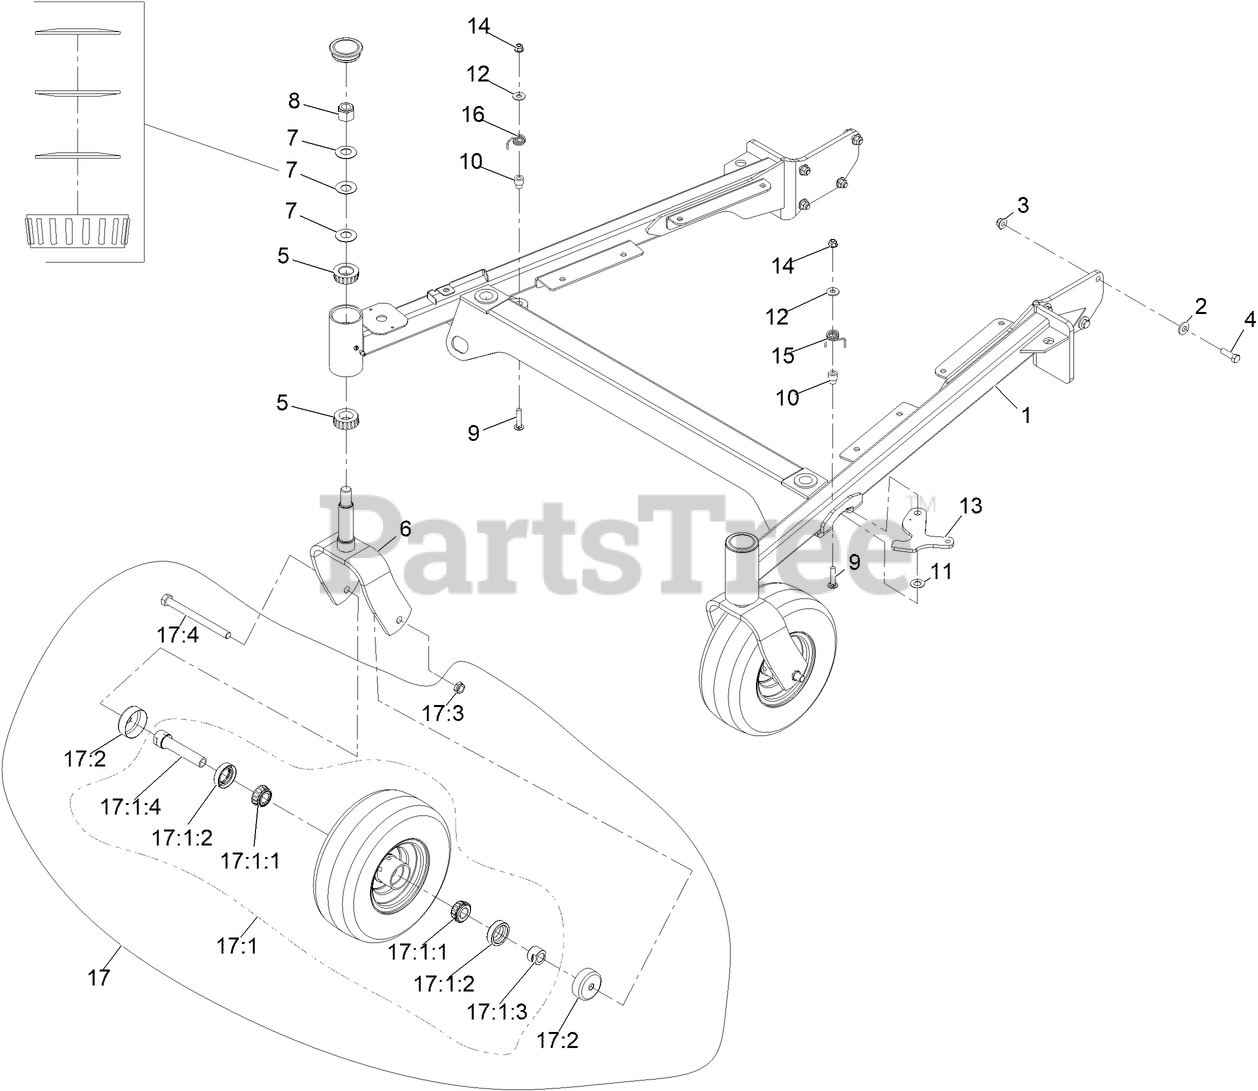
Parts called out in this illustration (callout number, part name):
1	ASM,FRONT FRAME W/BUSHING,60
2	WASHER-BELLEVILLE
3	NUT-HF, NI
4	SCREW-HH
5	Cone-Bearing Tapered Roller
6	WLD, CASTER FORK
7	WASHER-BELLVILLE
8	NUT-LOCK, NI
9	BOLT-CARR
10	COLLAR-BASKET
11	Washer-Plastic
12	WASHER-FLAT
13	LATCH, DECK HEIGHT
14	NUT-HF, NI
15	SPRING-TORSION, LH (YELLOW)
16	Spring-Torsion, RH
17	WHEEL AND TIRE ASM
17:1	WHEEL AND BEARING ASM
17:1:1	BEARING-CONE, TAPERED ROLLER
17:1:2	SEAL-CASTER
17:1:3	SPACER-NUT
17:1:4	CASTER AXLE ASM
17:2	GUARD-SEAL
17:3	NUT-HEX
17:4	SCREW-HH
